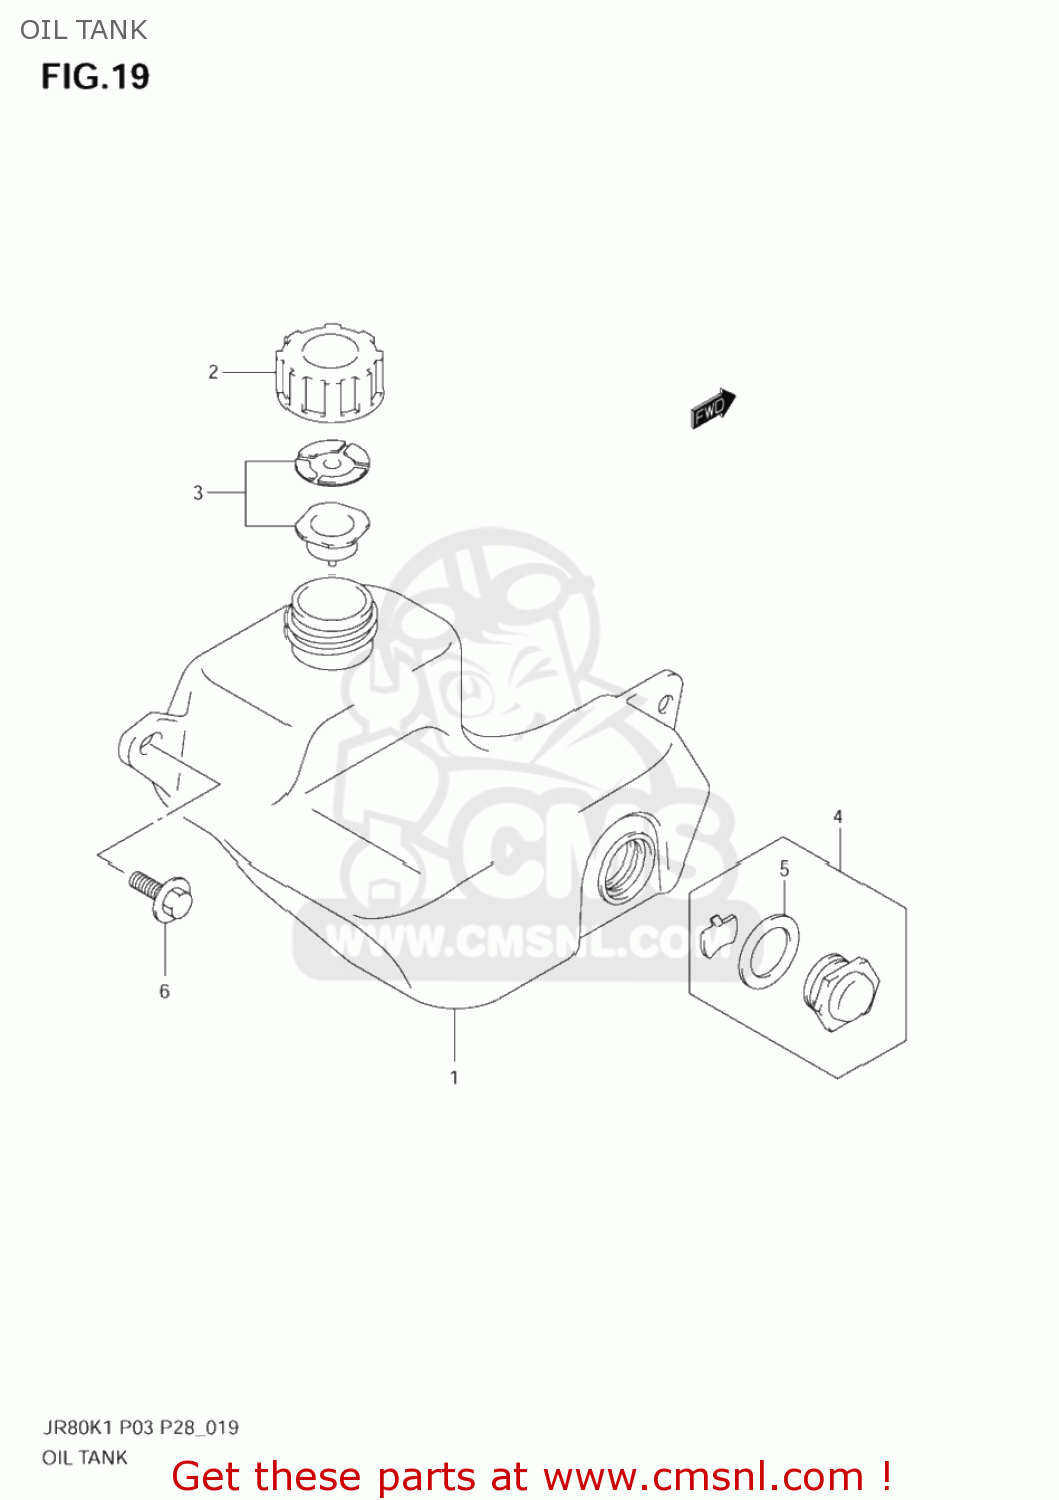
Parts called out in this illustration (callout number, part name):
1	TANK,OIL
2	CAP,OIL TANK
3	GASKET SET (NAS)
4	LENS SET,OIL LEVEL
5	GASKET (NAS)
6	BOLT(6X16)
